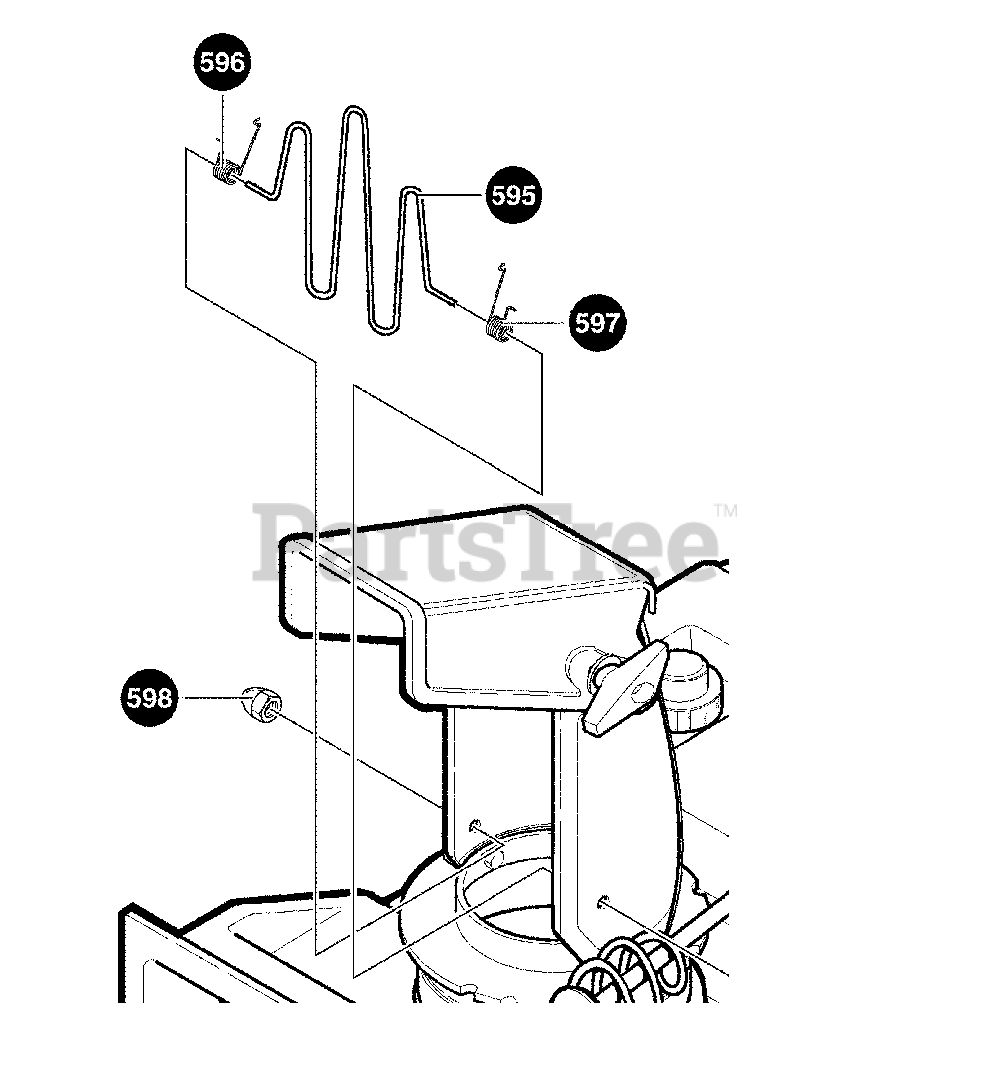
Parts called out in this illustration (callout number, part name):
595	GUARD, WIRE CHUTE
596	SPRING, TORSION
597	SPRING, TORSION
598	NUT, ACORN
